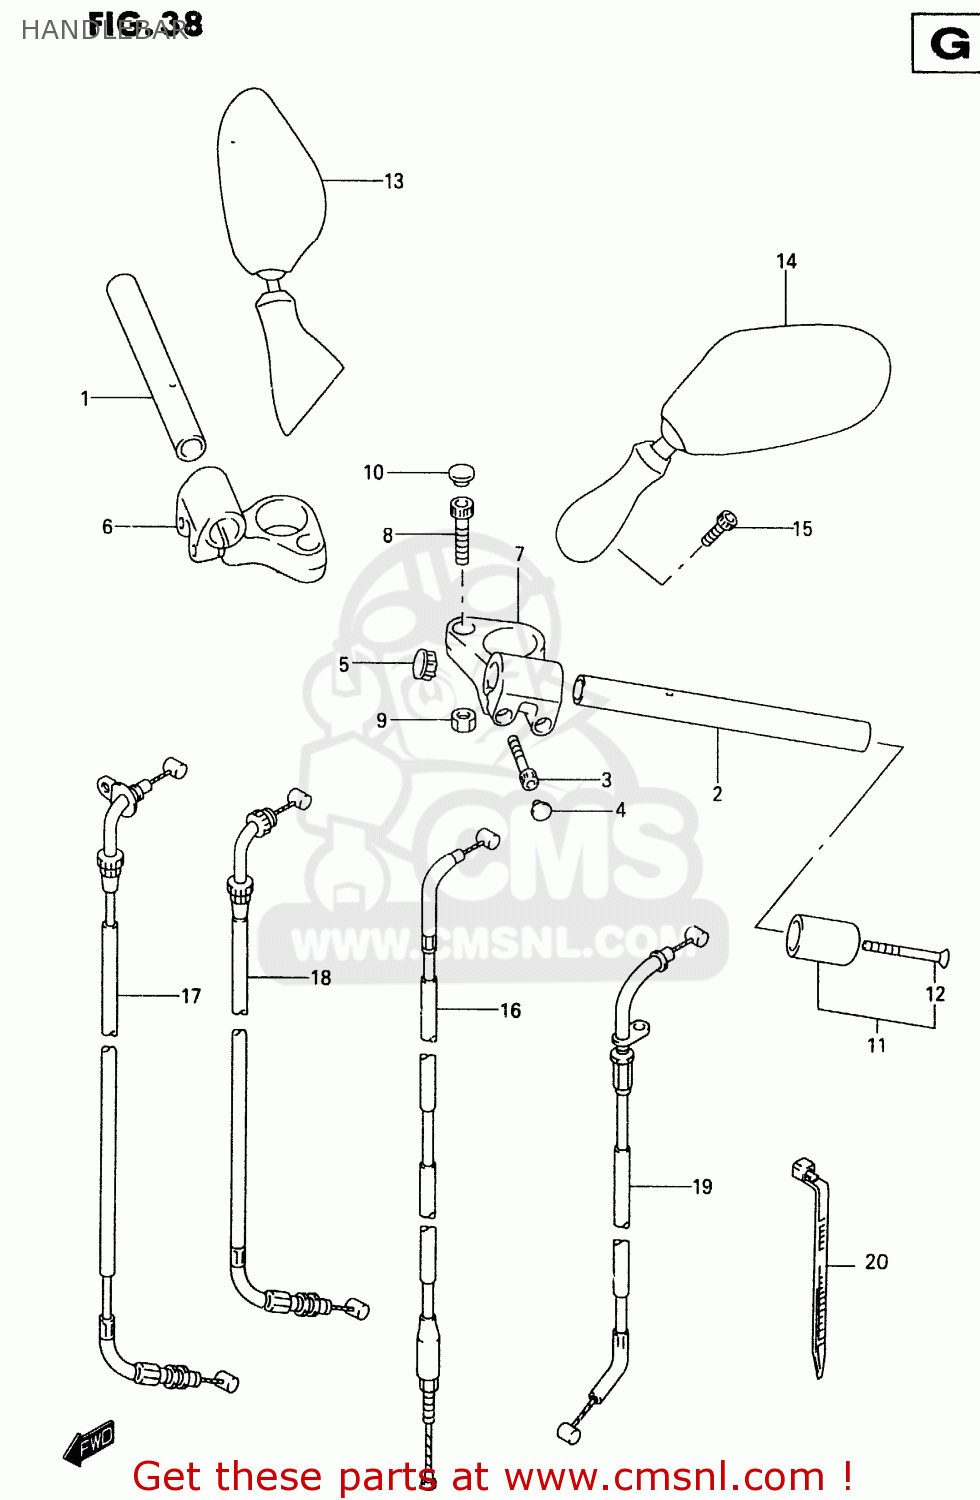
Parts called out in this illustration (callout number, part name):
1	HANDLEBAR COMP,RIGHT
2	HANDLEBAR COMP,LEFT
3	BOLT
4	CAP(OD:10)
5	CAP,HANDLEBAR
6	HOLDER,HANDLE,RIGHT
7	HOLDER,HANDLE,LEFT
8	BOLT 10X45
9	NUT
10	CAP(OD:20)
11	BALANCER SET,HANDLEBAR
12	SCREW
13	MIRROR ASSY,RR VIEW,R
14	MIRROR ASSY,RR VIEW,L
15	BOLT,OIL FILLE
16	CABLE ASSY,CLUTCH
17	CABLE ASSY,THROTTLE NO.1
18	CABLE ASSY,THROTTLE NO.2
19	CABLE,STARTER
20	CLAMP(L:125)
